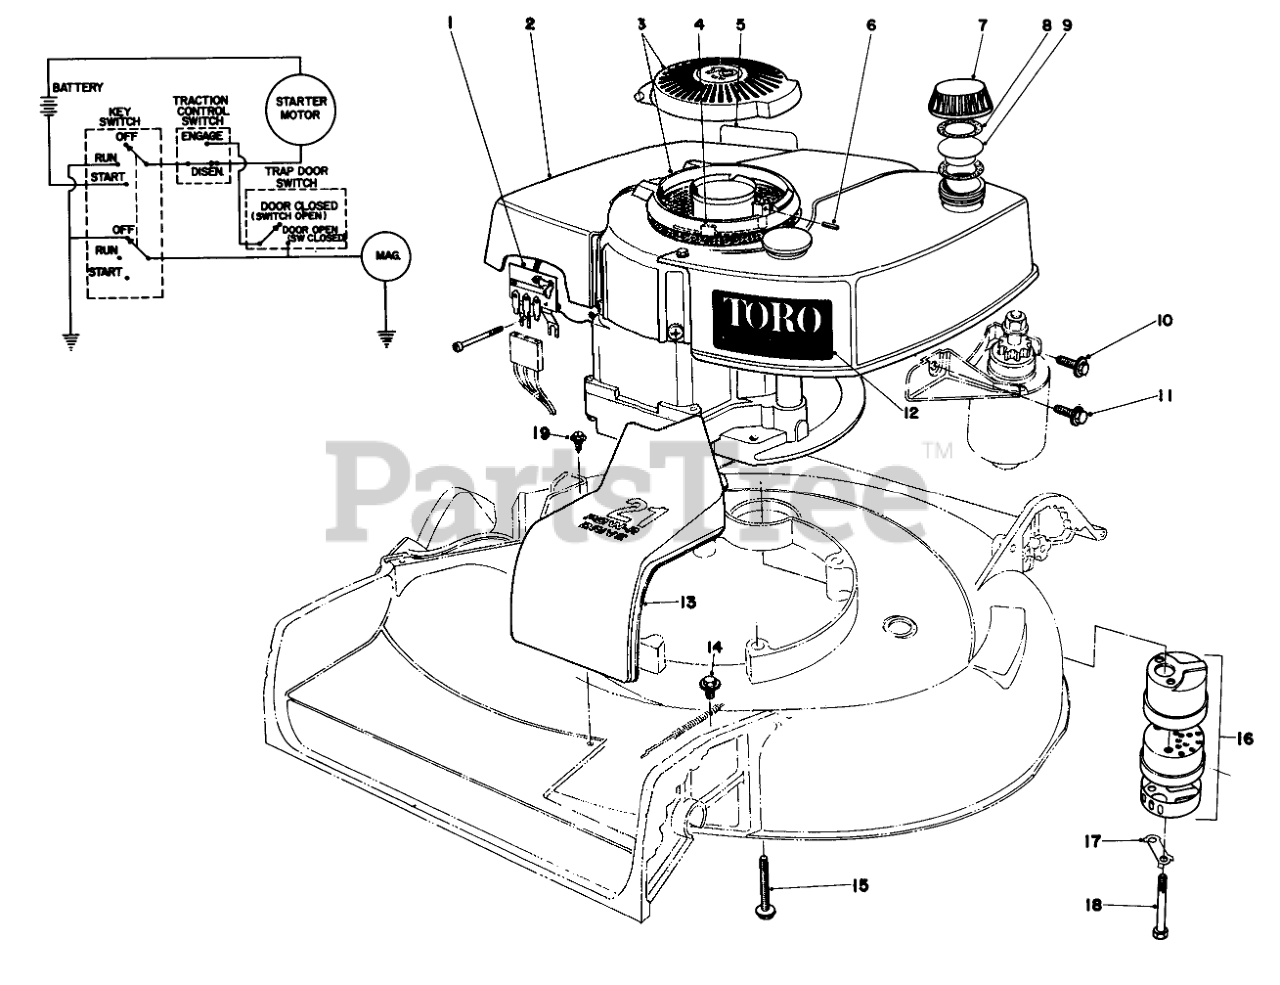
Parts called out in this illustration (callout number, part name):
1	SWITCH & TERM BLK CVR
2	Engine
3	Decal-Maintenan
4	Cover Assembly
5	WIRE CLIP
6	SPRING PIN
7	Gas Cap (Incl. Ref. #8 & 9)
8	GASKET
9	GAS CAP BAFFLE
10	SCREW
11	Screw
12	Decal
13	Cover Belt Drive
14	SCREW-HWHTF
15	3/8-16 X 2-3/4 CAPSCR
16	Muffler Assy . (Incl . Ref . #17& 18)
17	CLIP - LOCKING
18	SCREW-HH
19	SCREW
